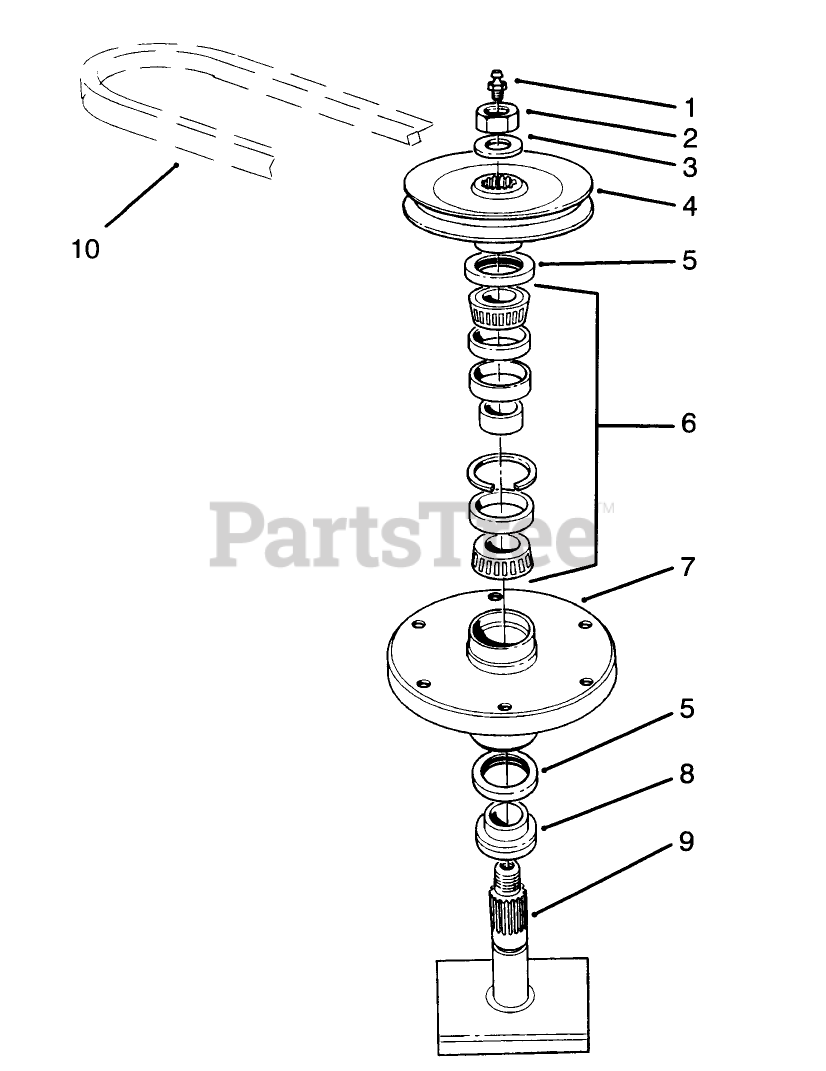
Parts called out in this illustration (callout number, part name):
1	FITTING-GREASE
2	NUT-HEX
3	WASHER
4	PULLEY AND HUB ASM
5	SEAL-OIL
6	BEARING ASM
7	HOUSING-SPINDLE
8	SPACER
9	SHAFT
10	V-BELT-DRIVE, DECK
